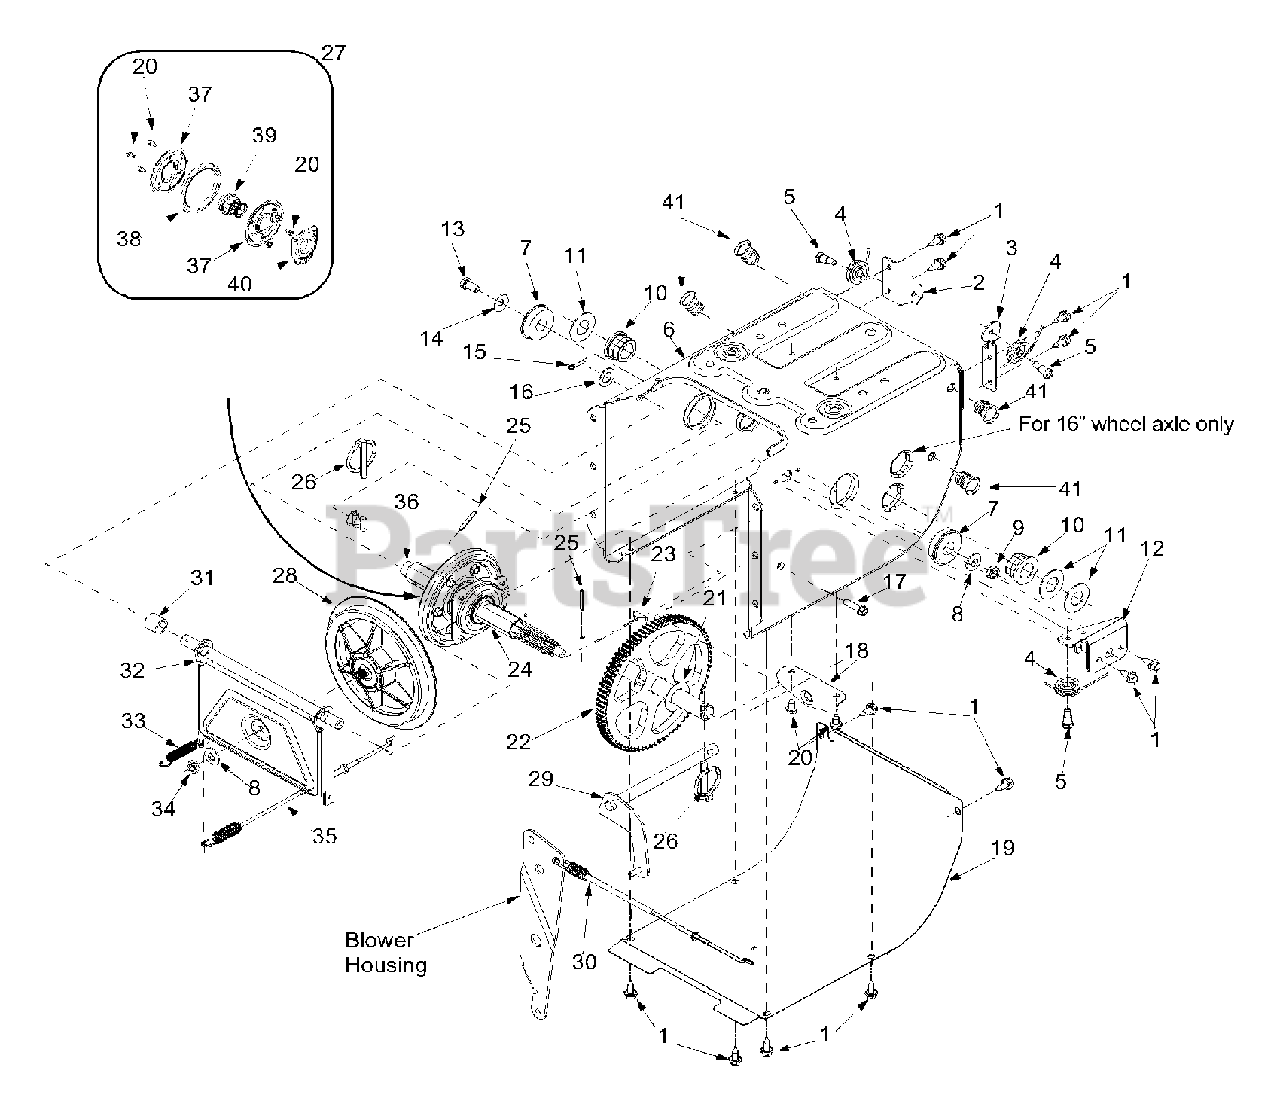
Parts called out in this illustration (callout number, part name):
1	Self-Tapp. Screw 1/4-20 x 0.5"
5	Hex Screw 1/4-28
8	Bell Washer
9	Lock Jam Nut
10	Hex Flange Bearing
11	Flat Washer
14	Bell Washer .340 ID x .872 OD
15	Cotter Pin
16	Flat Washer .536 ID x .930 OD
17	Hex Washer Screw 1/4-20 x .625"
21	Flat Washer .760 ID x .50 OD
24	7-Tooth Shaft
25	Roll Pin
26	Klik Pin
27	Friction Wheel Assembly
28	Friction Disc Wheel
29	Wheel Shift Rod Assembly
30	Drive Cable, Auger
31	Spacer
34	Jam Nut 3/8-24
35	Drive Cable, Clutch
36	22 .2" Axle (Used w/ 13 x 4 tire)
36	21.4" Axle (Used w/ 13 x 5 tire)
37	Friction Plate
38	Friction Wheel Rubber
39	Friction Wheel Hub
40	Friction Wheel Bearing
41	Nut Insert
